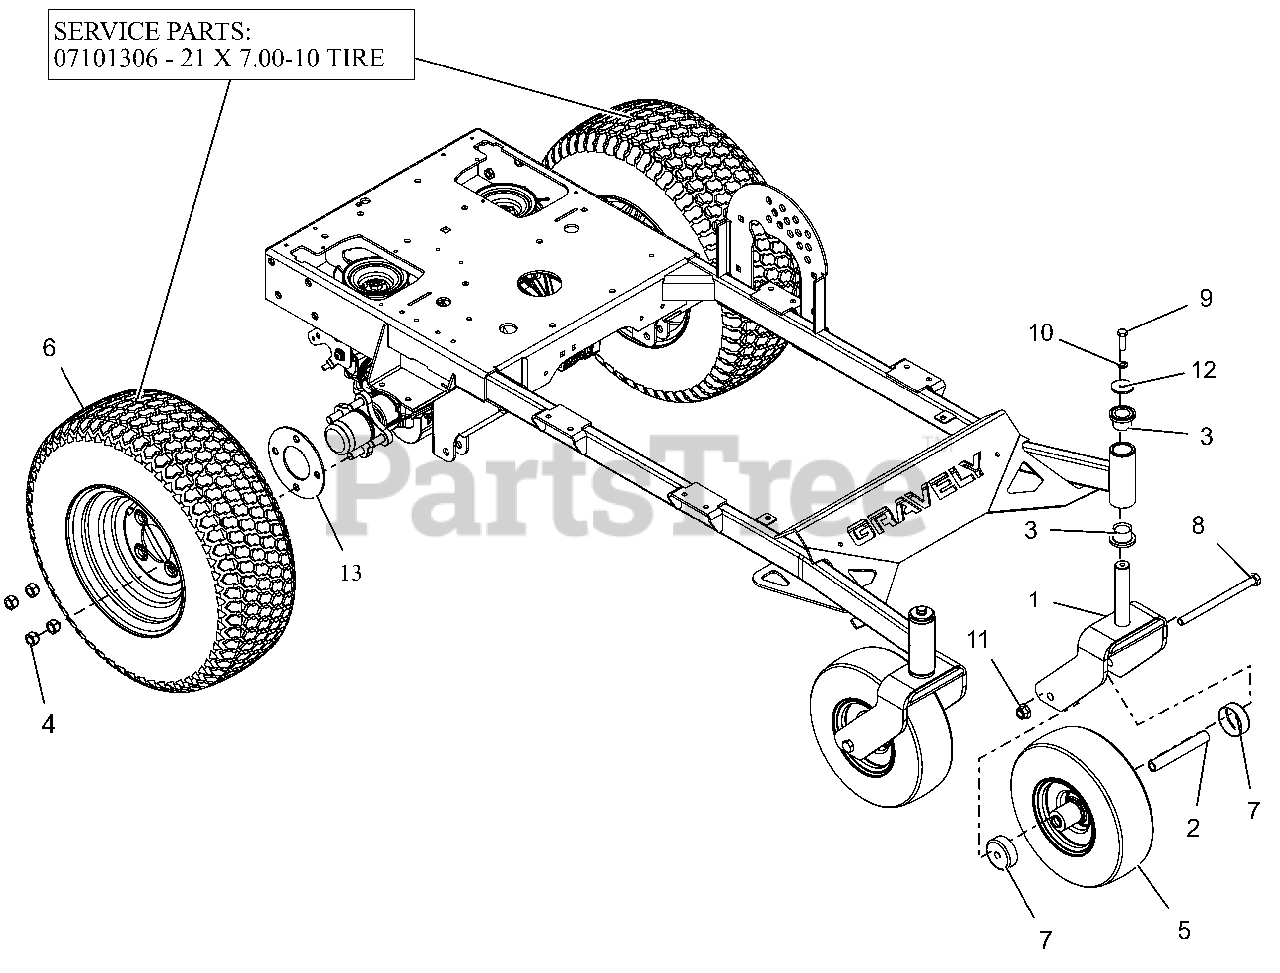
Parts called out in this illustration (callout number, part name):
1	WLDMT, CASTER FORK (RED)
2	SPACER, ROLLED WHEEL
3	BRG, FLG 1.00 X 1.25 X 1.00
4	WHEEL NUT .500-20 YZ
5	ASM, WHL/TIRE 11X4.00-5
6	ASSY, TIRE/WHL 21X7.00-10
6	TIRE, 21 X 7.00-10
7	SHIELD, WHEEL BEARING
8	@BLT-HEX .50-13X7.00 GR5 YWZC
9	@BLT-HEX .38-16X1.25 GR5 YWZC
10	@WSHR-LK .38X.094 REG YWZC
11	@NUT-LK-NYL-FLG .50-13 YWZC
12	WSHR-FL-STL .380X1.50X.125YWZC
13	SPACER, WHEEL 4-BOLT
